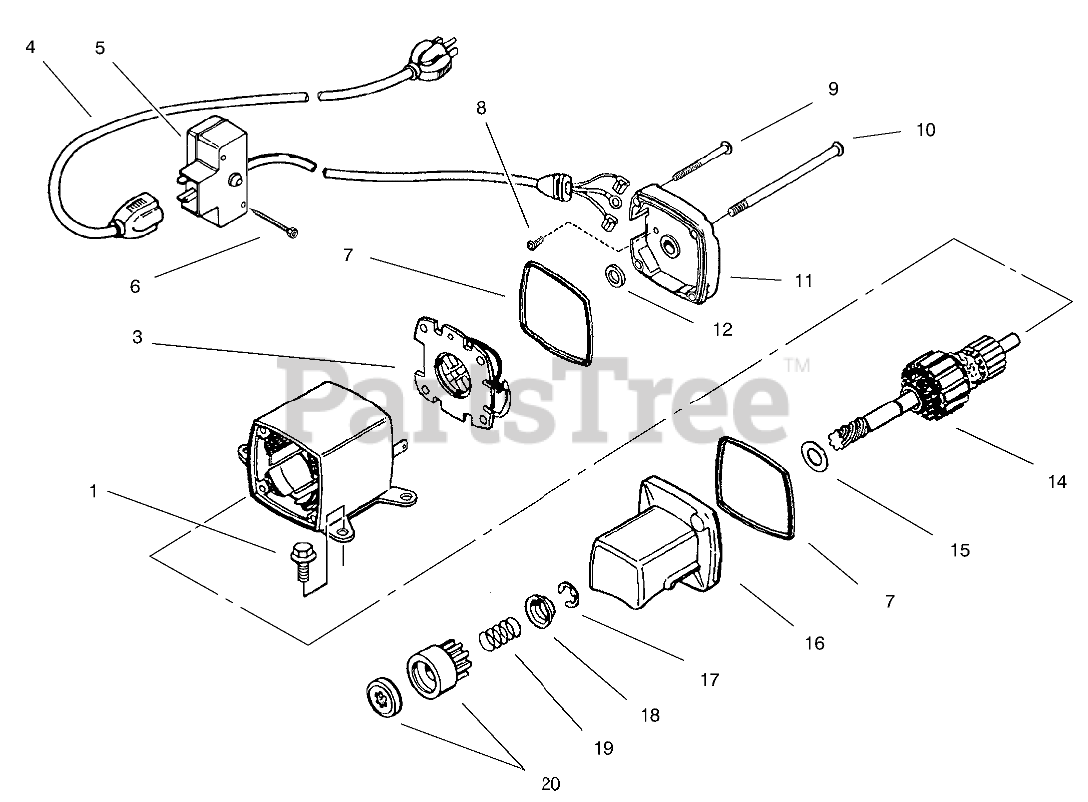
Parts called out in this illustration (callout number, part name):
1	Screw (T-30, 1/4-20 x 23/32)
3	Brush Card ASM
4	Cord-Extension (10-6)
5	Switch Box Asm (Incl. Ref. # 6)
6	Screw
7	O-Ring
8	Screw-Ground
9	Screw-Ground
10	Bolt-Case
11	Cap-Commutator End Asm (Incl. Ref. #7)
12	Washer-Thrust
14	Armature
15	Washer-Thrust
16	Cap-Drive End (Incl. Ref.# 7)
17	Retainer-Ring
18	Retainer-Spring
19	Spring-Anti Drift
20	Nut & Gear
